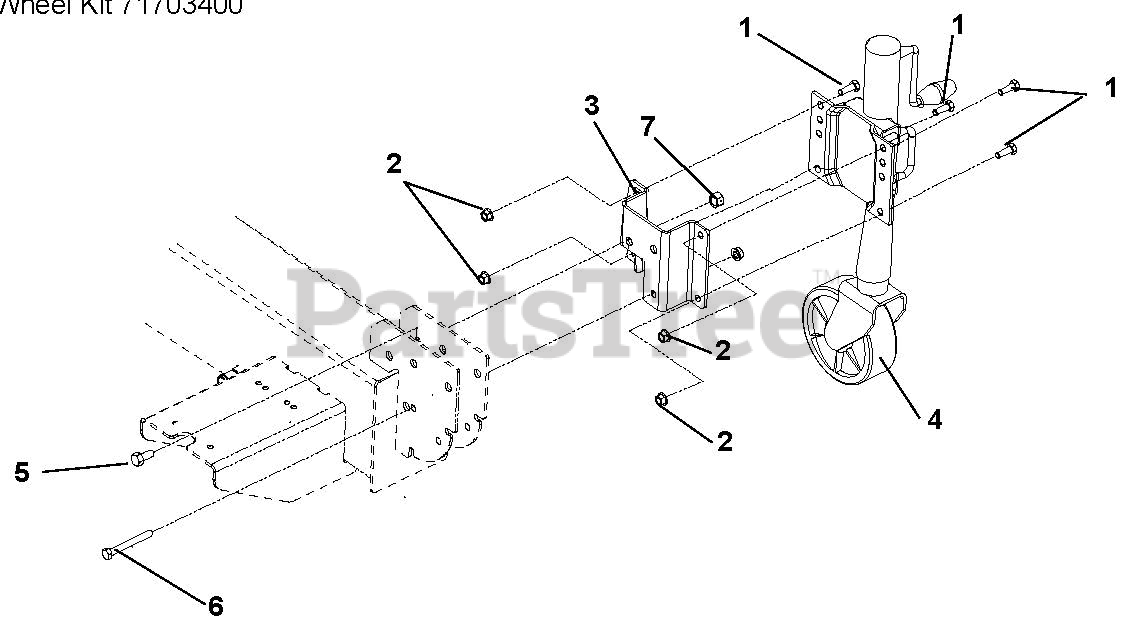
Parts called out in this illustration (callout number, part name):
1	@BLT-HEX .38-16X1.00 GR5 YWZC
2	@NUT-LK-TOP-FLG .38-16 YWZC
3	BRACKET, MOUNTING
4	STAND, JACK-W/WHEEL
5	@BLT-HEX .50-13X1.00 GR5 YWZC
6	@BLT-HEX .38-16X3.25 GR5 YWZC
7	NUT-LK-CTR-FLG .50-13 YWZC
